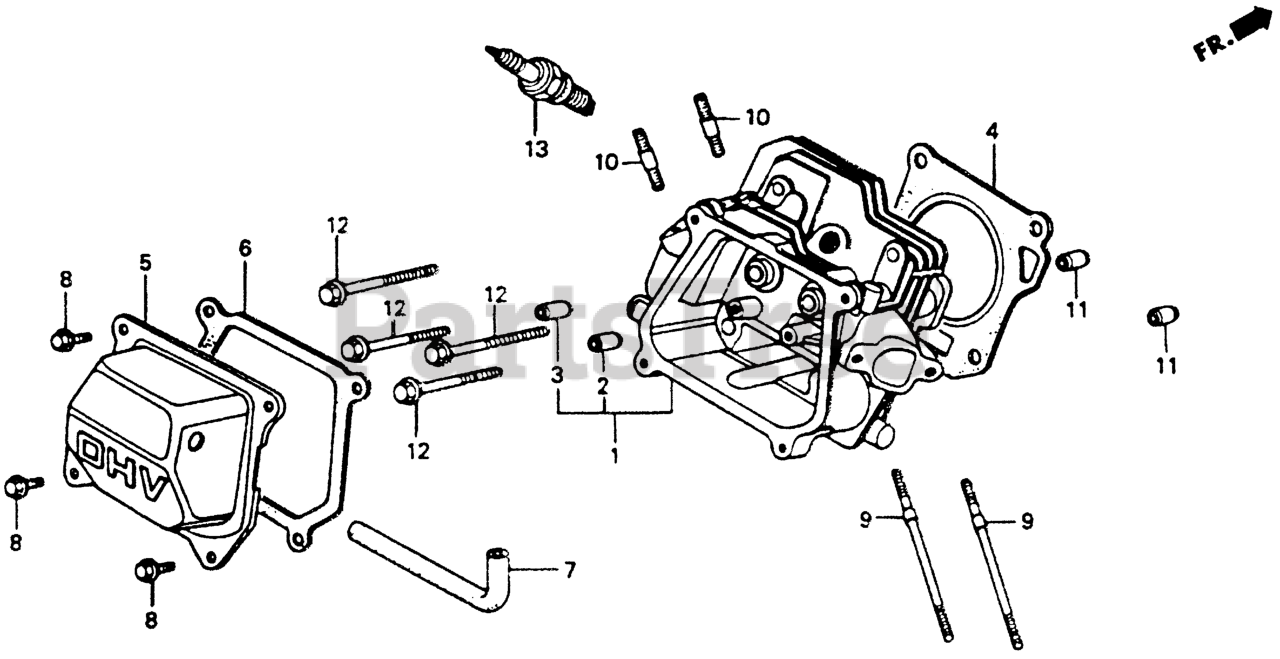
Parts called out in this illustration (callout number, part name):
1	CYLINDER HEAD (NOT AVAILABLE)
1	CYLINDER HEAD
2	GUIDE, VALVE (OVER SIZE) Use up to Engine SN 2416541.
3	GUIDE, EX. VALVE (OVER SIZE)
4	GASKET, CYLINDER HEAD
5	COVER, HEAD
6	GASKET, CYLINDER HEAD COVER
7	TUBE, BREATHER
8	BOLT, FLANGE (6X12) (CT200)
8	BOLT, FLANGE (6X13)
9	BOLT, STUD (6X109)
10	BOLT, STUD (8X32)
11	PIN A, DOWEL (10X16)
12	BOLT, FLANGE (8X60)
13	SPARK PLUG (BPR6ES) (NGK)
13	SPARK PLUG (W20EPR-U) (DENSO)
